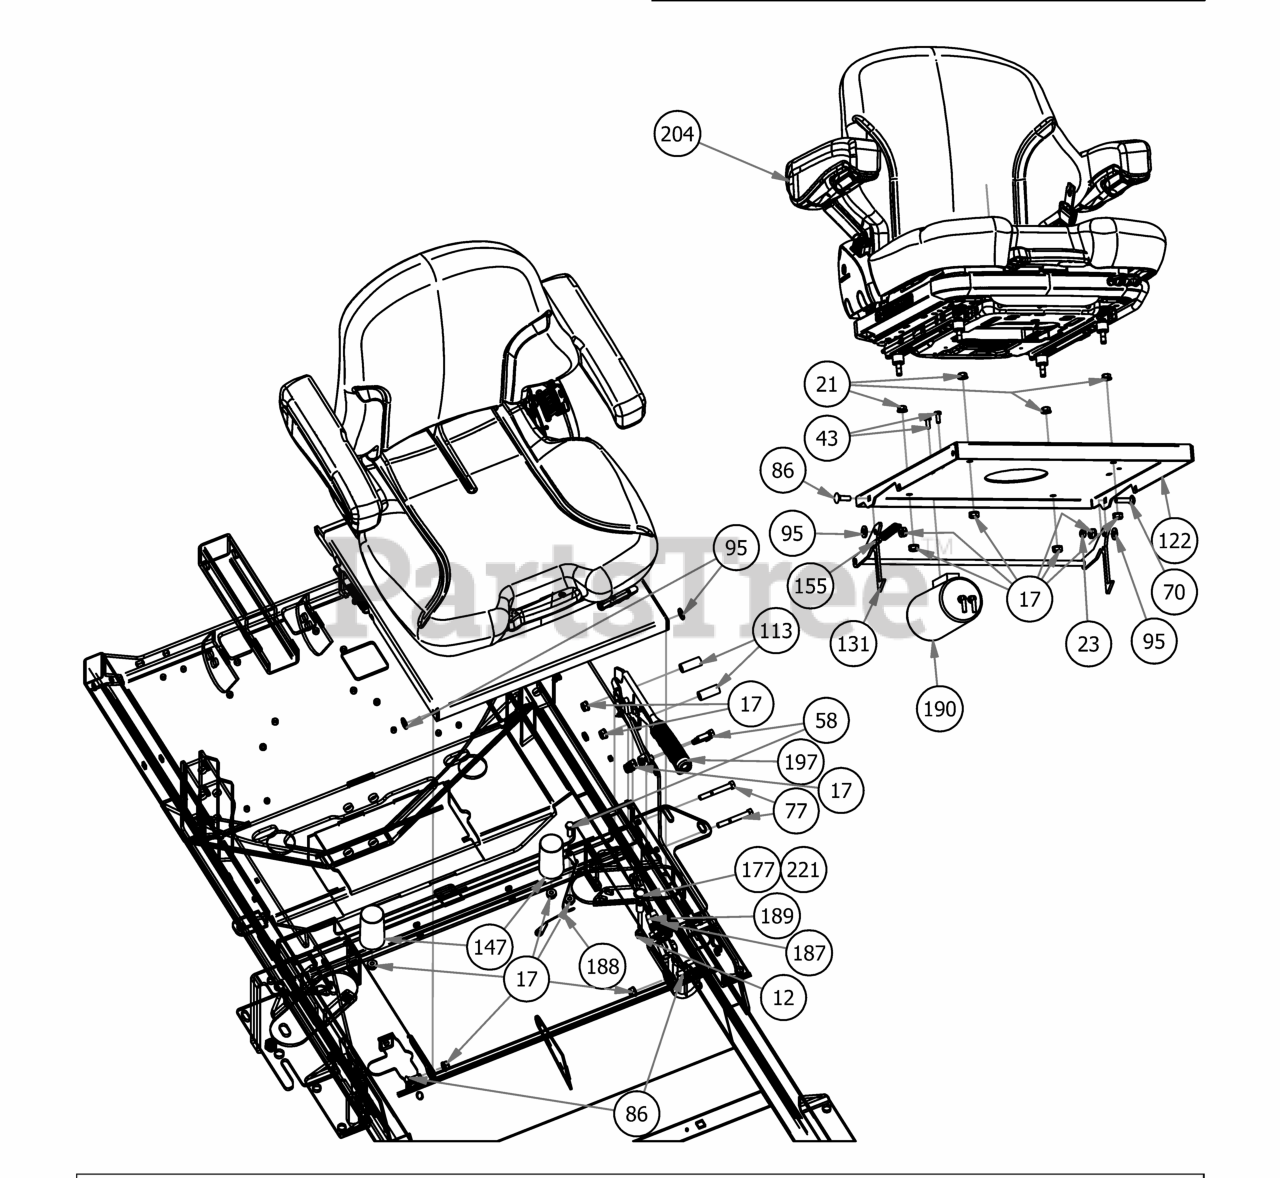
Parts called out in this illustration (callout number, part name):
12	3/8" Fine Threaded Jam Nut
17	5/16-18 Nylon Flange Nut
21	5/16" Flange Nut
23	5/16-18 Nylock Jam Nut 1/2 Nut
43	M6-1.0 X 16MM Hex Bolt
58	5/16" x 1" Bolt
70	5/16" x 1 1/4" Carriage Bolt
77	5/16" x 2 1/2" Bolt
86	5/16" x 1" Carriage Bolt
95	.360 ID Plastic Washer
113	2019 Outlaw Brake Handle Spacer .625 x 1.5
122	2019 Outlaw Seat Plate
131	Seat Latch Rod Assembly
147	2019 Bad Boy X Cylindrical Seat Mount
155	Brake Spring
177	Choke for 36Hp Vanguard & FX1000 Kawasaki
187	2019 Short Brake Cable-Suspension Models
188	Seat Cable
189	2019 Long Brake Cable-Renegade, Rogue
190	2019 Outlaw EPA Cannister Assembly
197	2019 Brake Handle Assembly
203	2019 Horizontal Gas Frame
204	2019 Renegade Seat
221	Code Indicator Light
